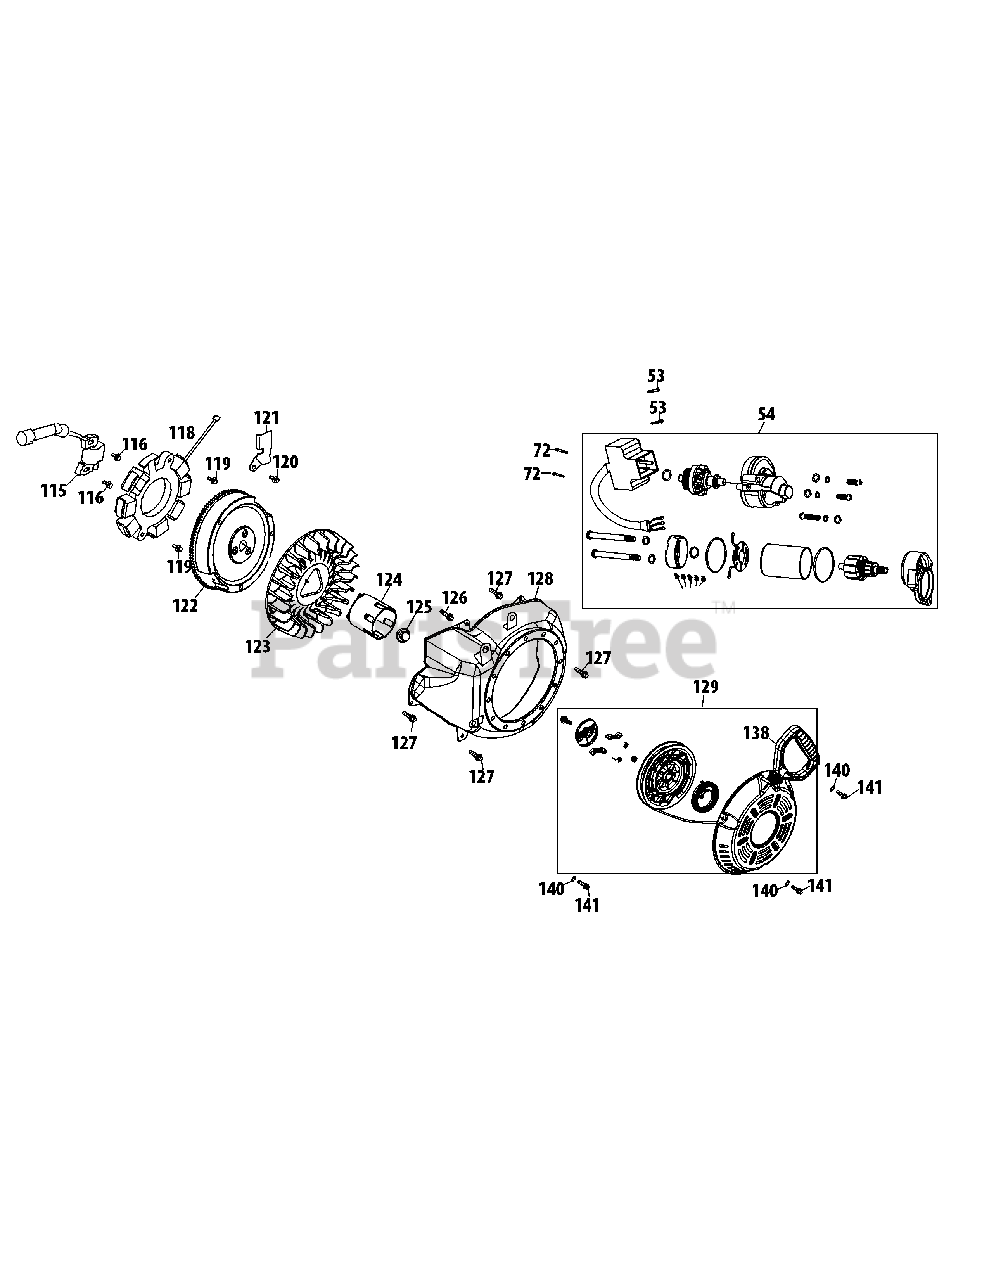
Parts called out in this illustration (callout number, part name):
53	Bolt M4×55
54	Electric Starter
72	Bolt M8×55
115	Ignition Coil Assembly
116	Ignition Coil Bolt
118	Alternator Assembly
119	Bolt M6×30
120	Bolt M6×8
121	Wire Plate
123	Cooling Fan
124	Starter Cup
125	Flange Nut
126	Bolt M6×16
127	Bolt M6×12
128	Blower Housing
129	Recoil Starter Assembly
138	Starter Handle
140	Gasket 6
141	Bolt M6×10
